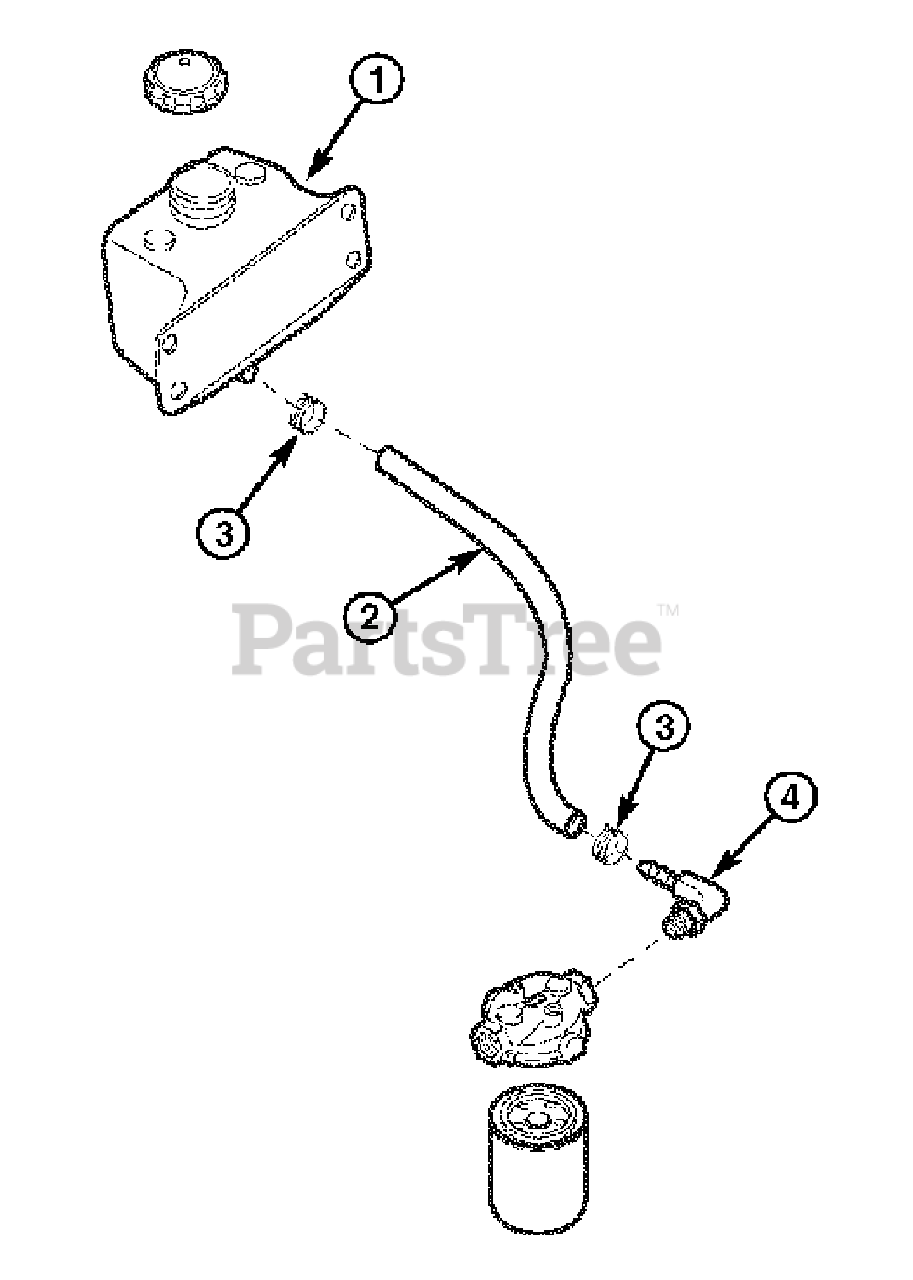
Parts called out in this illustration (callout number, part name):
1	TANK, 2 Quart Hydraulic
2	HOSE, 5/8 Push-on, 13 Length
3	CLAMP, Hose, 7/8
4	ADAPTER, 90 deg, 9/16-5/8 Barb
